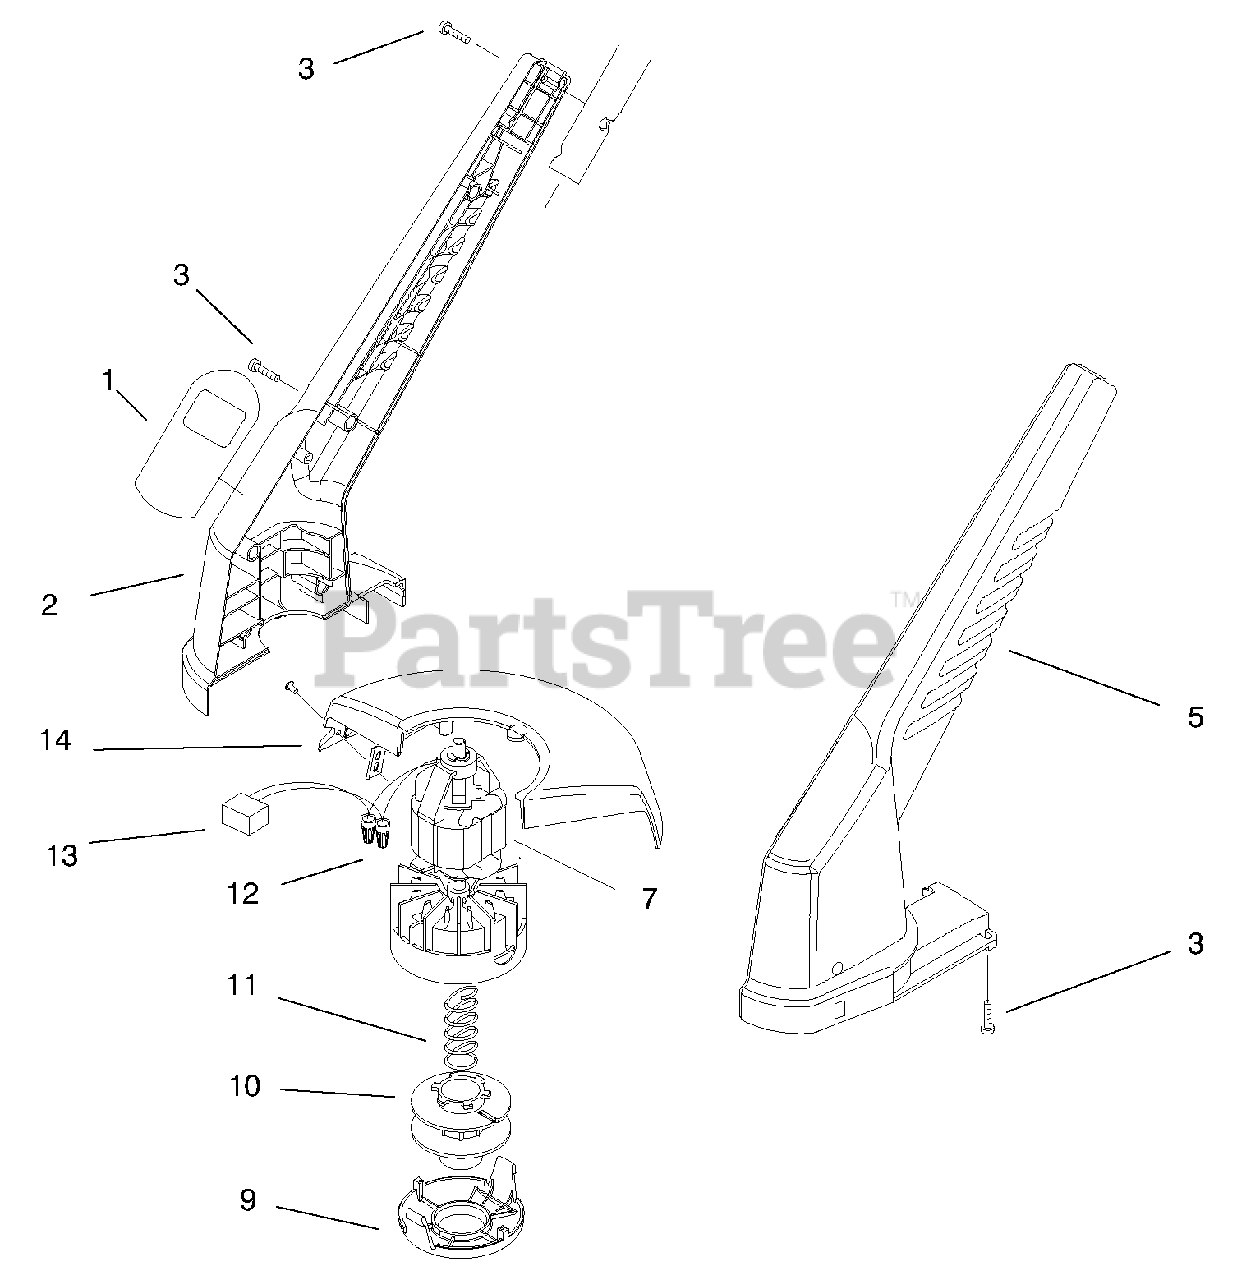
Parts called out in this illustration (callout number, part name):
1	Decal-25CM Trimmer
2	Housing R.H.
3	Screw-Pan Hd.
5	Housing L.H.
7	Motor Assembly-Trimmer
10	Spool
12	Connector-Wire Nut
